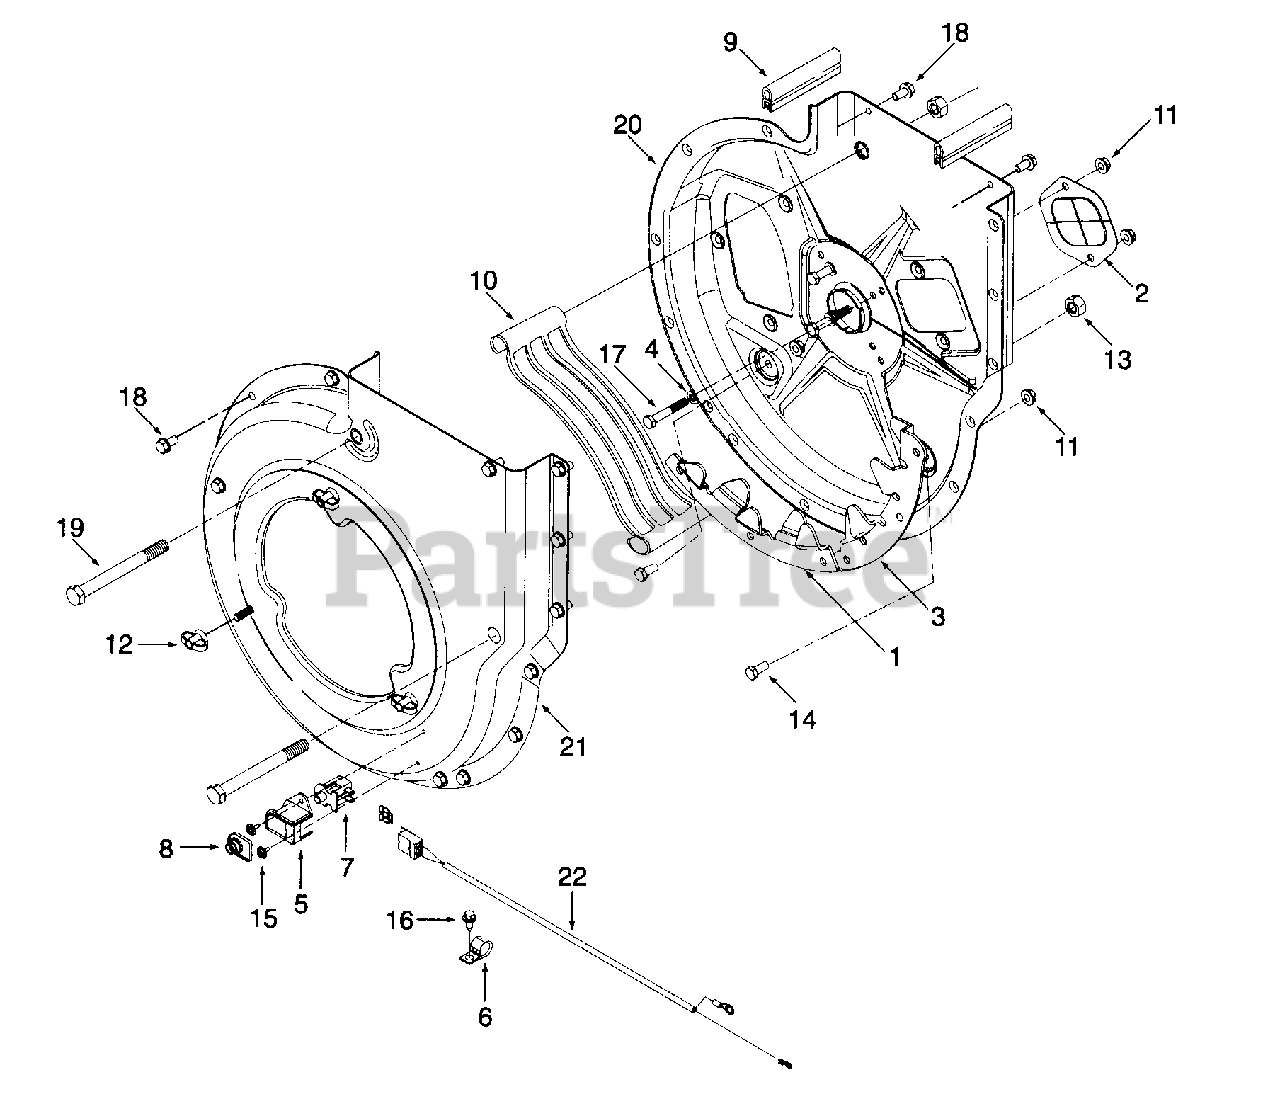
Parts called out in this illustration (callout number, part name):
4	LOCK WASHER 5/16"
5	SAFETY SWITCH COVER
6	CLAMP 9/16 DIA.
7	SAFETY SWITCH SNAP MOUNT
8	SWITCH COVER
9	RUBBER SEAL
10	SCREEN
11	HEX FLANGE LOCK NUT 5/16-18
12	KNOB 5/16-18 X .70
13	HEX LOCK NUT 1/2-13
14	HEX HEAD CAP SCREW 5/16-18 X .75
15	HEX WASH TAPP-B SCREW #10-16 X .38
16	HEX IND. WASH-AB SCREW 1/4-14 X .625
17	HEX CAP SCREW 5/16-24 X 2.00
18	HEX IND. WASH-TT SCREW 5/16-18 X .62
19	HEX CAP SCREW 1/2-13 X 5.00
22	WIRE HARNESS
